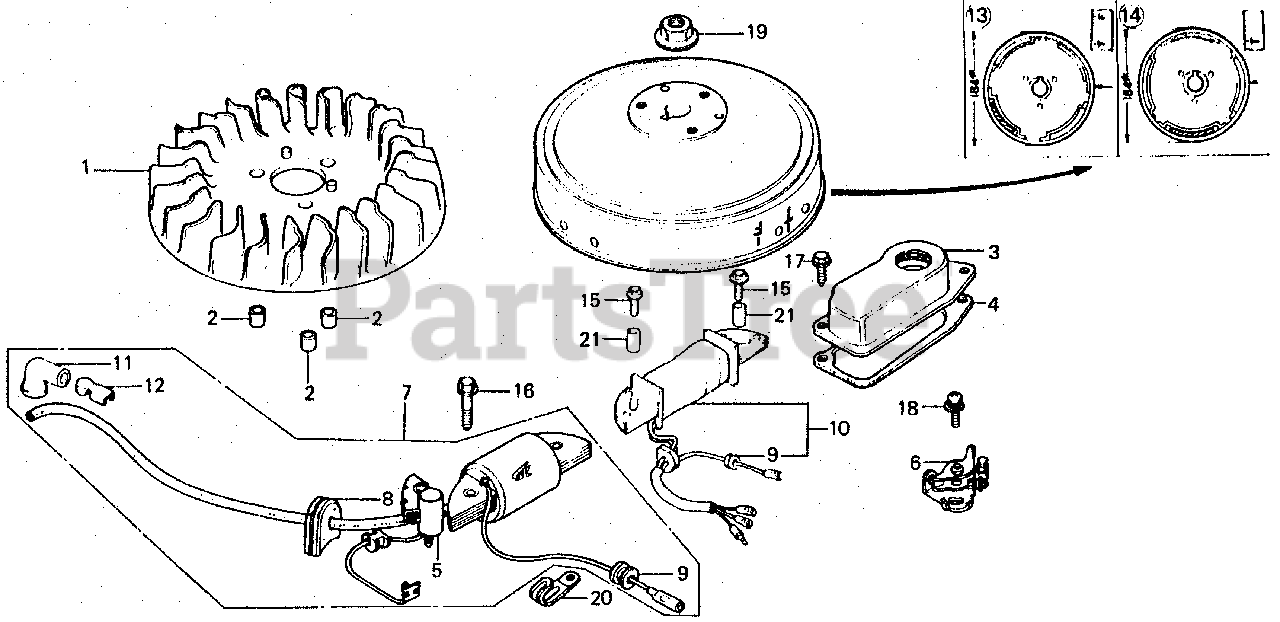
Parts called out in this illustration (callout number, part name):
1	FAN, COOLING
2	COLLAR, FAN
3	COVER, POINTS
4	GASKET, POINT COVER
6	POINTS ASSY.
7	COIL, IGNITION
8	GROMMET, WIRE
9	GROMMET, PRIMARY WIRE
11	CAP, IGNITION (TOYO)
12	TERMINAL, PLUG
16	BOLT, FLANGE (6X32)
17	BOLT, FLANGE (5X10)
18	SCREW-WASHER (5X12)
19	NUT, SPECIAL (14MM)
20	CLIP, CABLE
